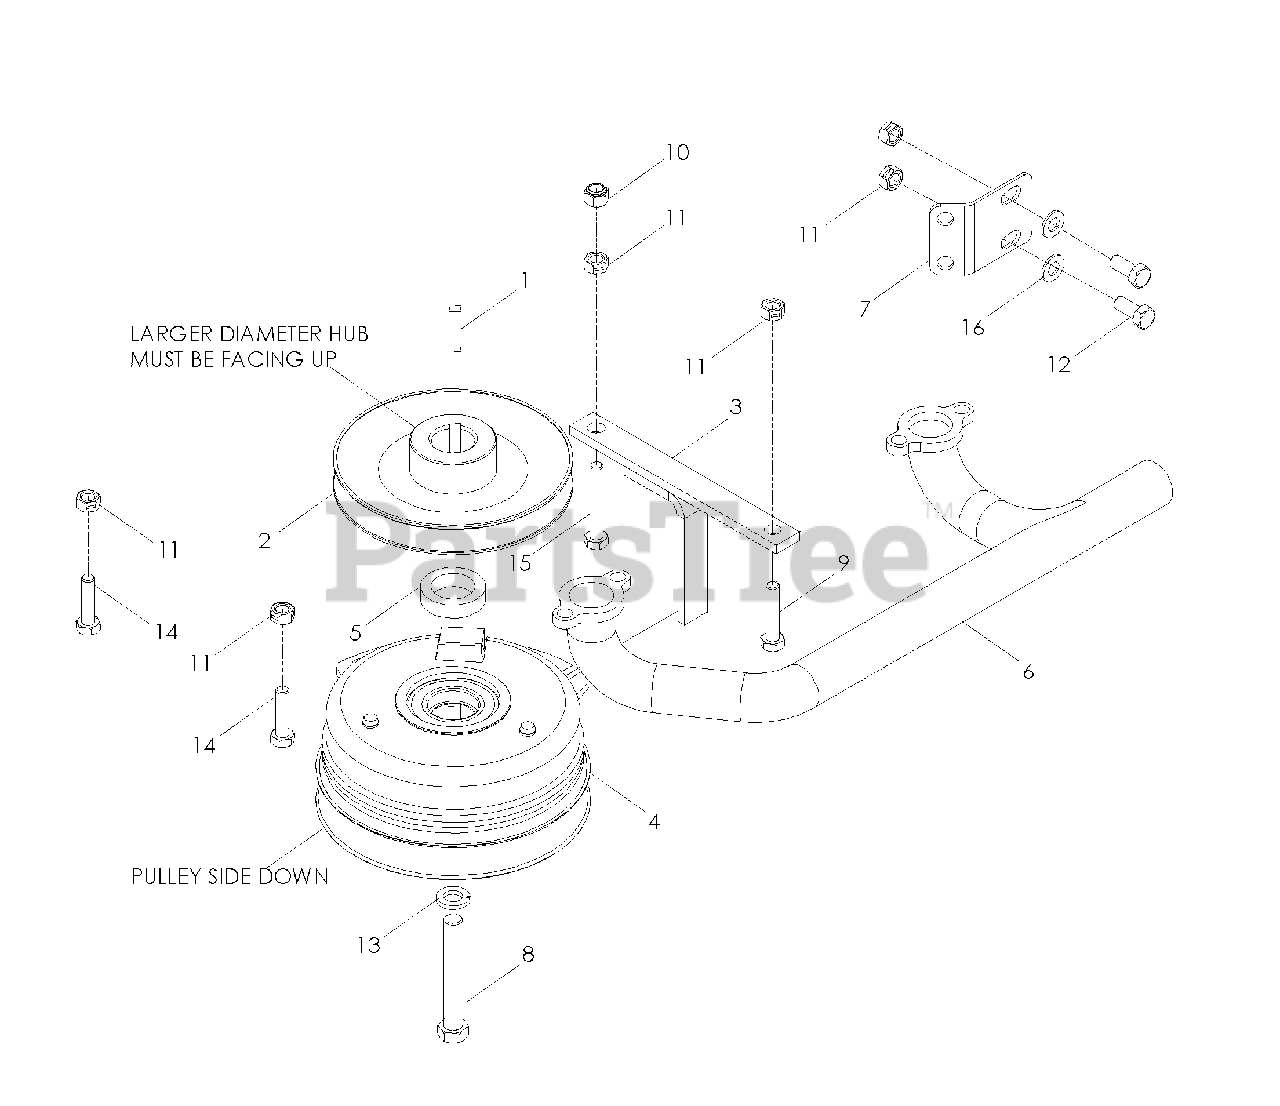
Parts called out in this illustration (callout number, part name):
1	KEY 1/4 SQ x 1 1/8
2	PULLEY, PUMP
3	TIE DOWN, CLUTCH
6	MANIFOLD, EXHAUST
7	BRACKET, MUFFLER
8	HCS 7/16-20 x 3
9	HCS 5/16-18 x 1 1/2
10	NUT 5/16-18 HEX NYLOC
11	NUT 5/16-18 HEX CTRLK
12	HCS 5/16-18 x 3/4
13	WASHER 7/16 SLW
14	HCS 5/16-18 x 1 1/4
15	HCS 5/16-18 x 2
16	WASHER 5/16 SAE FLAT
